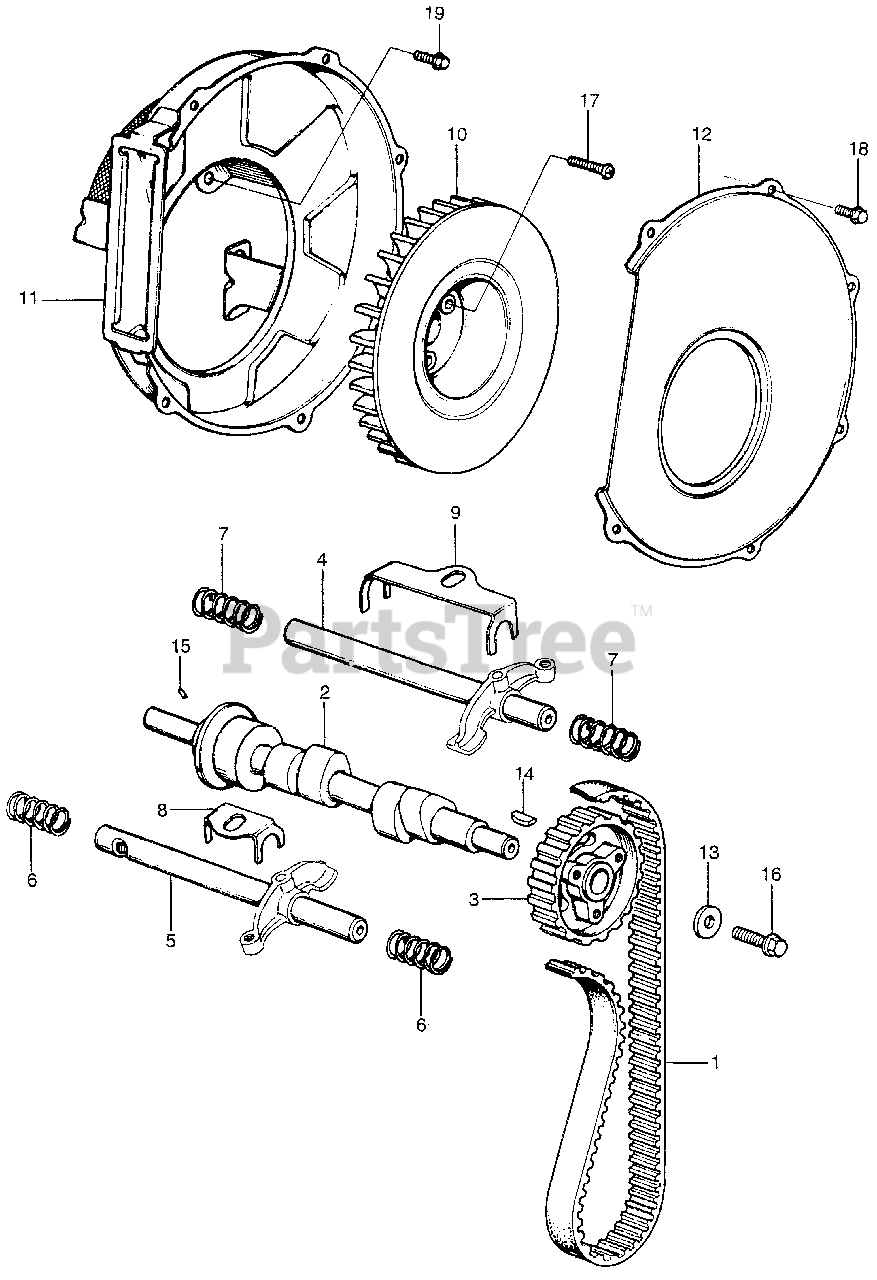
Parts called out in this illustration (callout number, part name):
1	BELT KIT (NOT AVAILABLE)
3	PULLEY, CAM
4	SHAFT, ROCKER ARM
5	SHAFT, EX. ROCKER ARM
6	SPRING, EX. ROCKER ARM
7	SPRING, IN. ROCKER ARM
8	WASHER, EX. THRUST
9	WASHER, IN. THRUST
10	FAN, COOLING
11	COVER, FAN
12	COVER, SIDE
13	WASHER, SPECIAL (28X8.5X4.0)
14	KEY, WOODRUFF (30x16.8MM) (NOT AVAILABLE)
15	PIN, KNOCK (3X6.5)
16	BOLT, HEX. (8X20)
17	SCREW, PAN (6X28)
18	BOLT, FLANGE (6X10)
19	BOLT, FLANGE (6X12)
